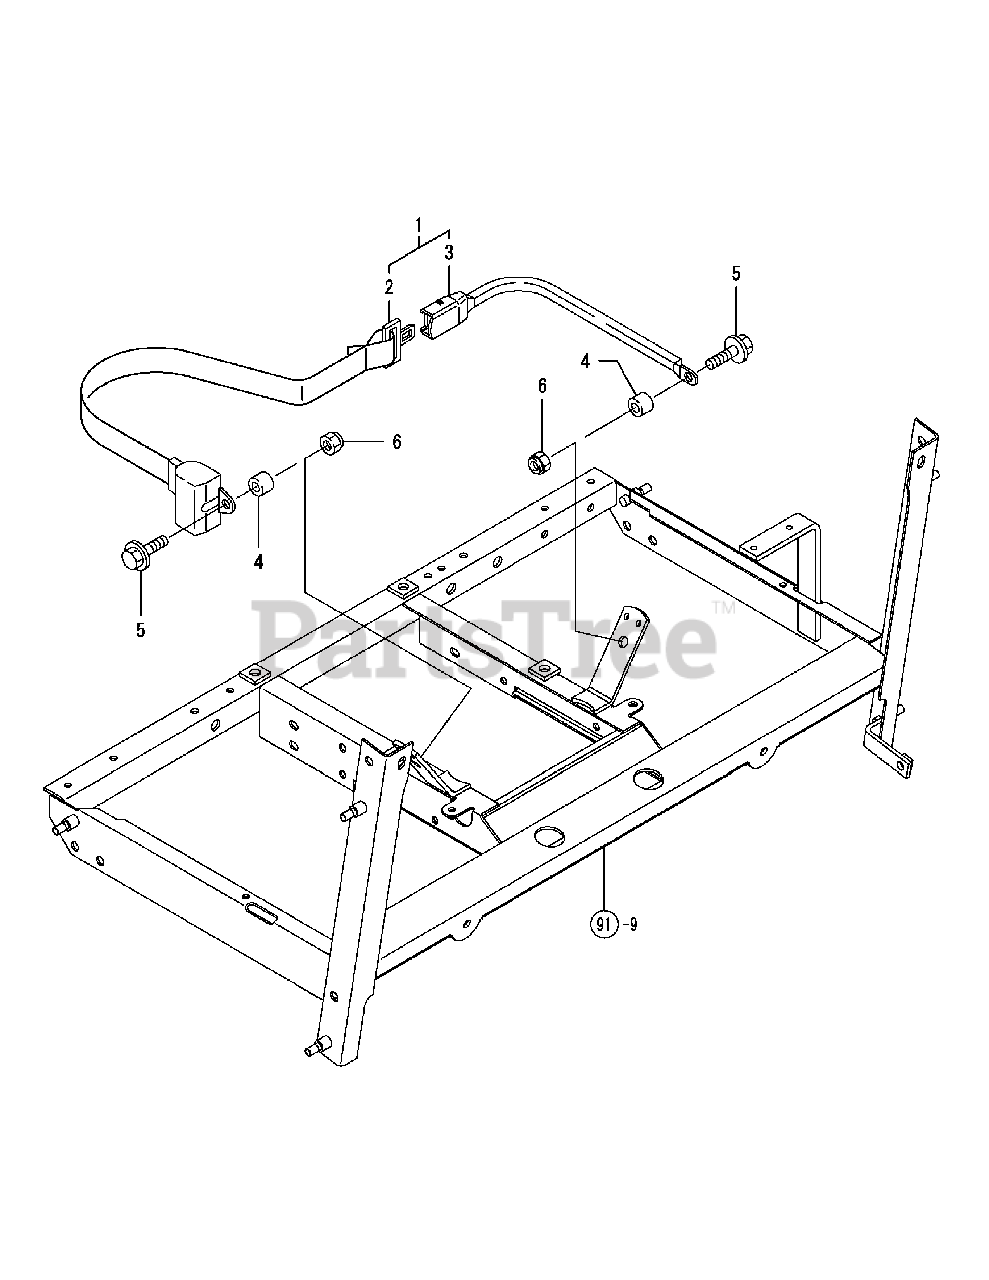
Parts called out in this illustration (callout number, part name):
1	SEAT BELT ASSY
3	BELT R,SAFETY CMP
4	COLLAR,SEAT BELT
5	BOLT M10X 35 PLATED
6	U-NUT M10 PLATED
